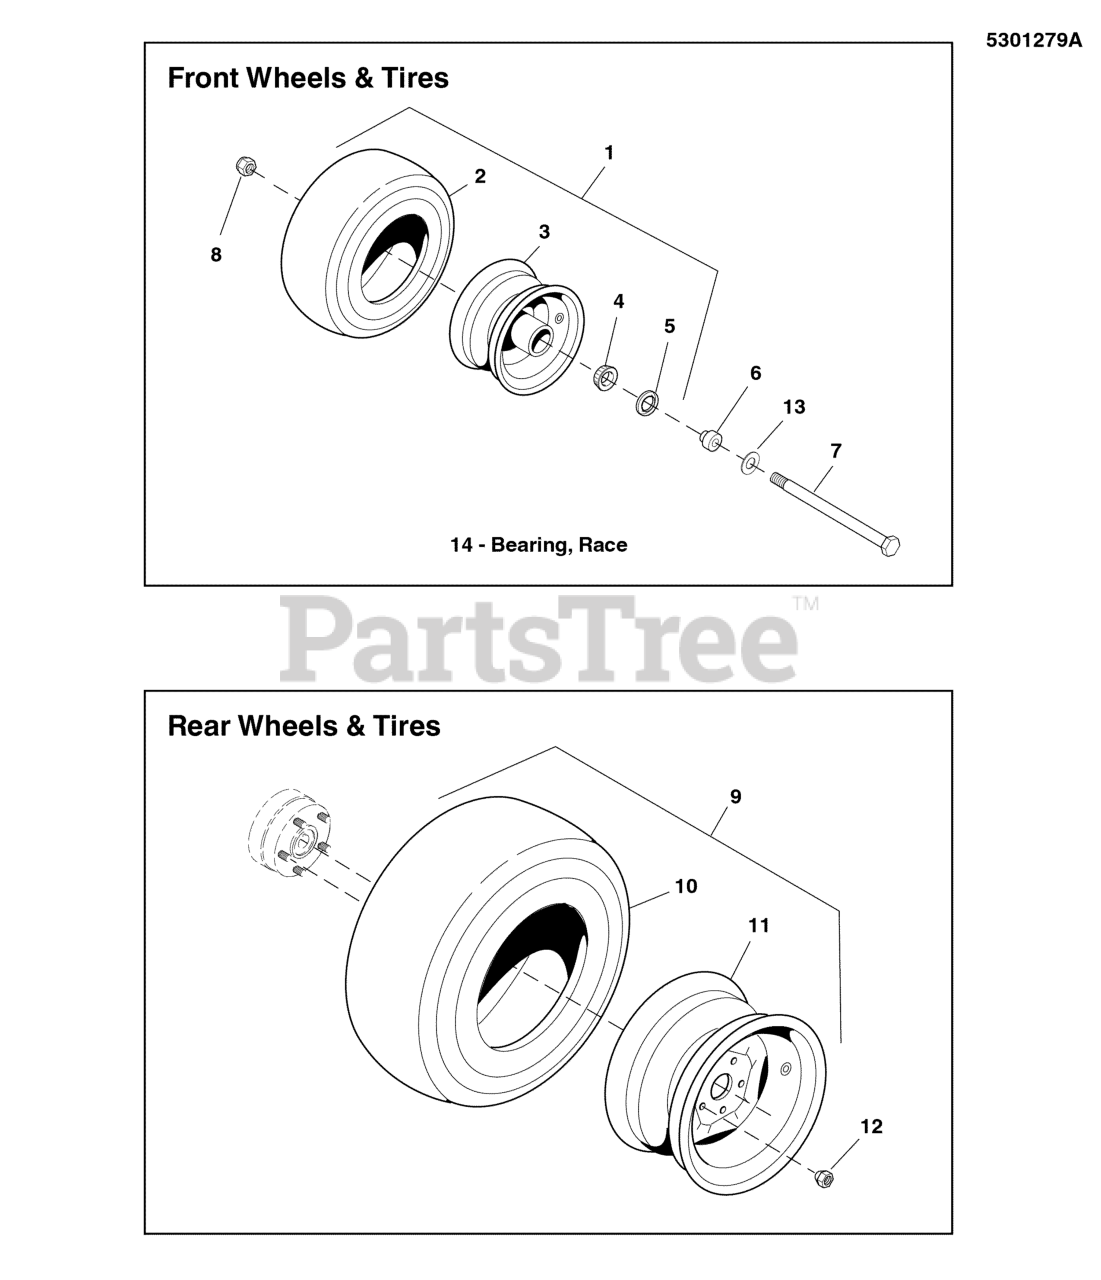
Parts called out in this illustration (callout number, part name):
1	TIRE, CASTER, 13 X 5.00-6
2	TIRE, 13 x 5.0 - 6 (SV)
3	WHEEL ASSEMBLY, for 13 x 5.0 - 6 Tire, Complete (SV)
4	BEARING, Tapered Roller
5	SEAL, GREASE
6	ADAPTER, CASTER AXLE, CZ
7	BOLT, 1/2-13 X 8 GD5 YZ (NLA)
8	NUT, Hex Flange, Nylock, 1/2-13
9	TIRE ASSM, 22 X 11.00-10
10	TIRE, 22 X 11.0 - 10 (SV)
11	RIM-10X7-5-4.5 SOLID (SV)
12	NUT, 1/2-20, FOR WHEEL BOLT SILVER
13	WASHER, 1/2 SAE
